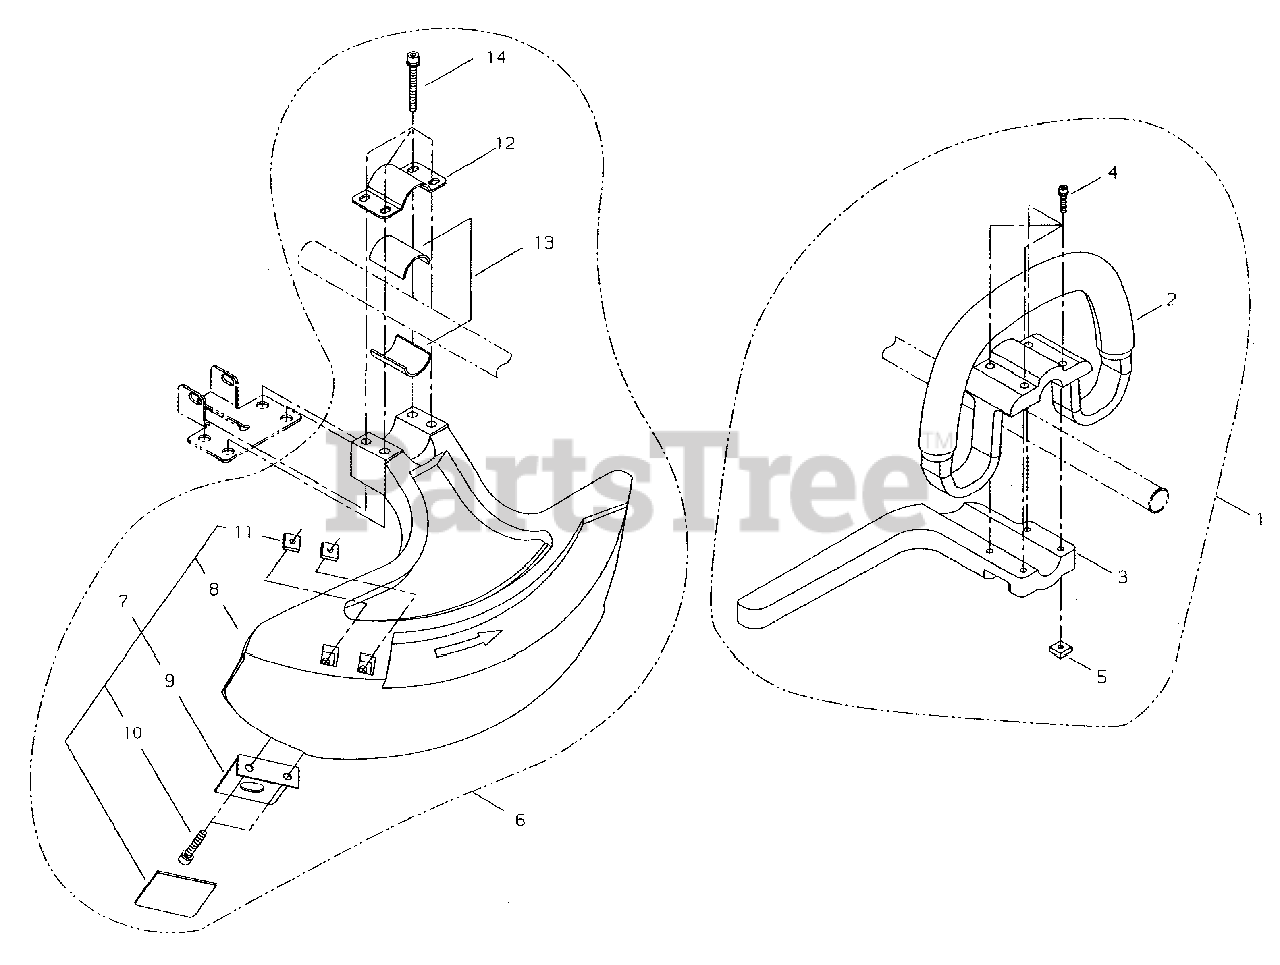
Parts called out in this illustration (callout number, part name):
1	HANDLE ASSY
2	HANDLE
3	BAR, BARRIER
4	BOLT M5×35
5	NUT M5
6	DEBRIS SHIELD KIT
7	DEBRIS SHIELD KIT
8	DEBRIS SHIELD KIT
9	CUTTER
10	BOLT M5×22
11	NUT M5
12	CLAMP, UPPER
13	SPACER 24
14	BOLT M5×45
